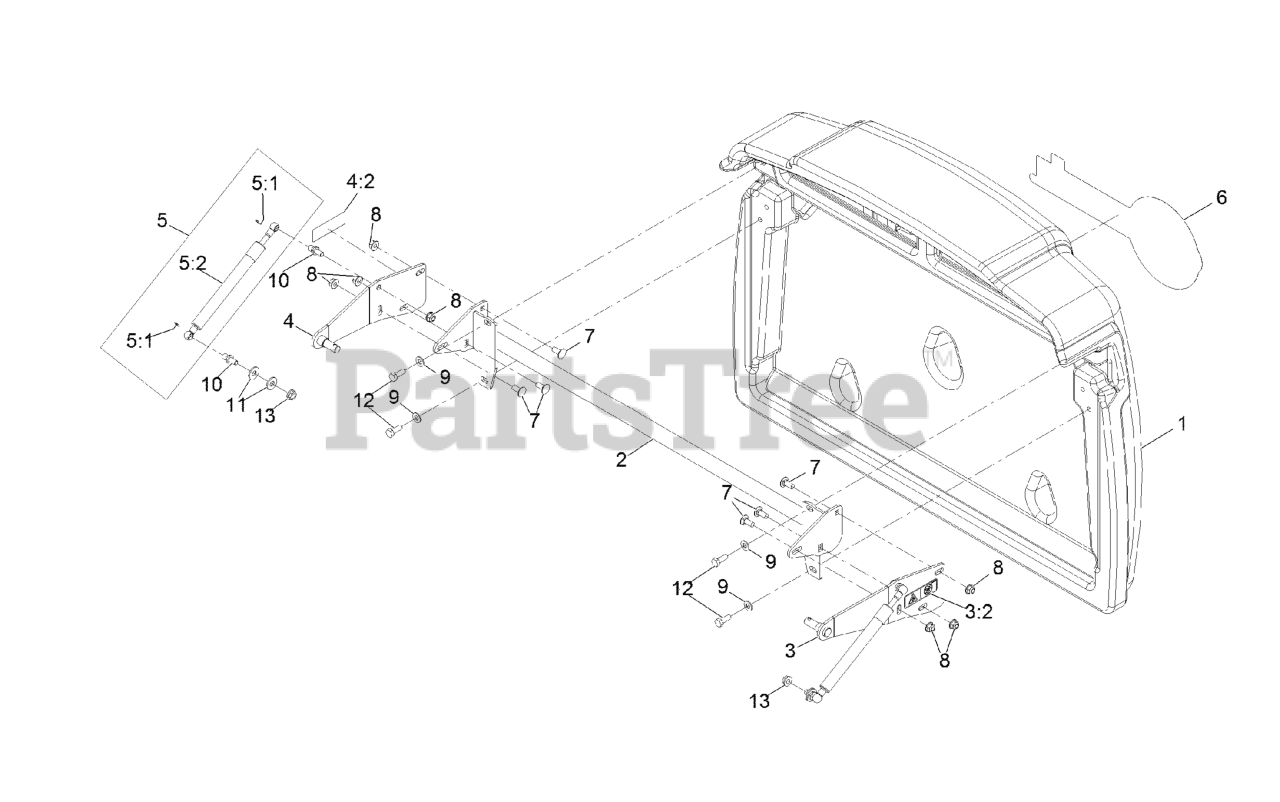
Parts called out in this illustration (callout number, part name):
1	DOOR,HOPPER
2	SUPPORT-DOOR
3	LH DOOR PIVOT ASM
3:2	DECAL-WARNING, PINCH POIN
4	RH DOOR PIVOT ASM
4:2	DECAL-WARNING, PINCH POIN
5	DAMPER KIT
5:1	CLIP-RETAINER
5:2	SHOCK-GAS TENSION
6	DECAL-EXMARK LOGO
7	SCREW-CARR
8	NUT-HF, NI
9	WASHER-PLAIN
10	STUD-BALL
11	WASHER-FLAT
12	SCREW-HH
